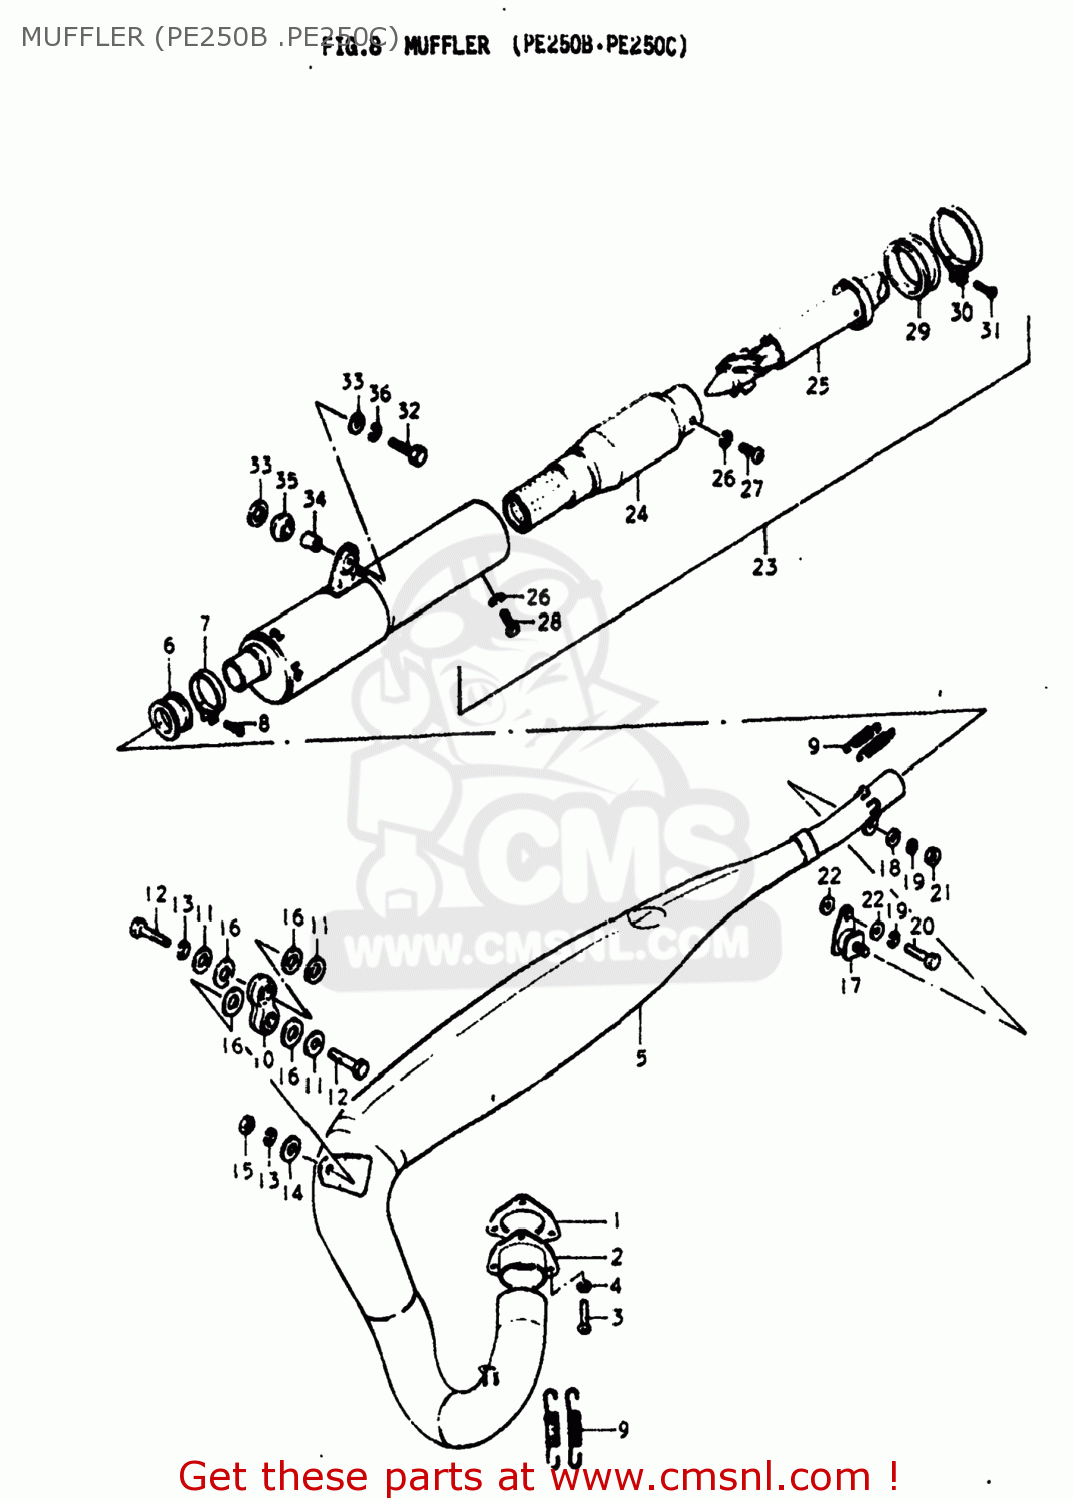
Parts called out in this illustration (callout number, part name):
1	GASKET,EXHAUST PIPE (MCA)
2	FLANGE,EXHAUST PIPE
3	SCREW
4	LOCK WASHER
5	BODY,MUFFLER
6	CONNECTOR,MUFFLER
7	CLAMP
8	SCREW
9	SPRING
10	DAMPER,MUFFLER
11	WASHER
12	BOLT
13	LOCK WASHER
14	WASHER
15	NUT
16	WASHER(13X28X1.6)
17	DAMPER,MUFFLER SUPPORT
18	WASHER
19	LOCK WASHER
20	BOLT 8X16
21	NUT
22	WASHER (8.2X20X1.6)
23	MUFFLER ASSEMBLY
24	ARRESTER,SPARK
25	TUBE,MUFFLER CLEAN OUT
26	LOCK WASHER
27	SCREW
28	SCREW(6X8)
29	CONNECTOR,SECOND MUFFLER
30	CLAMP
31	SCREW
32	BOLT (8X30)
33	WASHER (8.7X22X2)
34	SPACER (8X12X15)
35	DAMPER,MUFFLER,FR
36	LOCK WASHER
